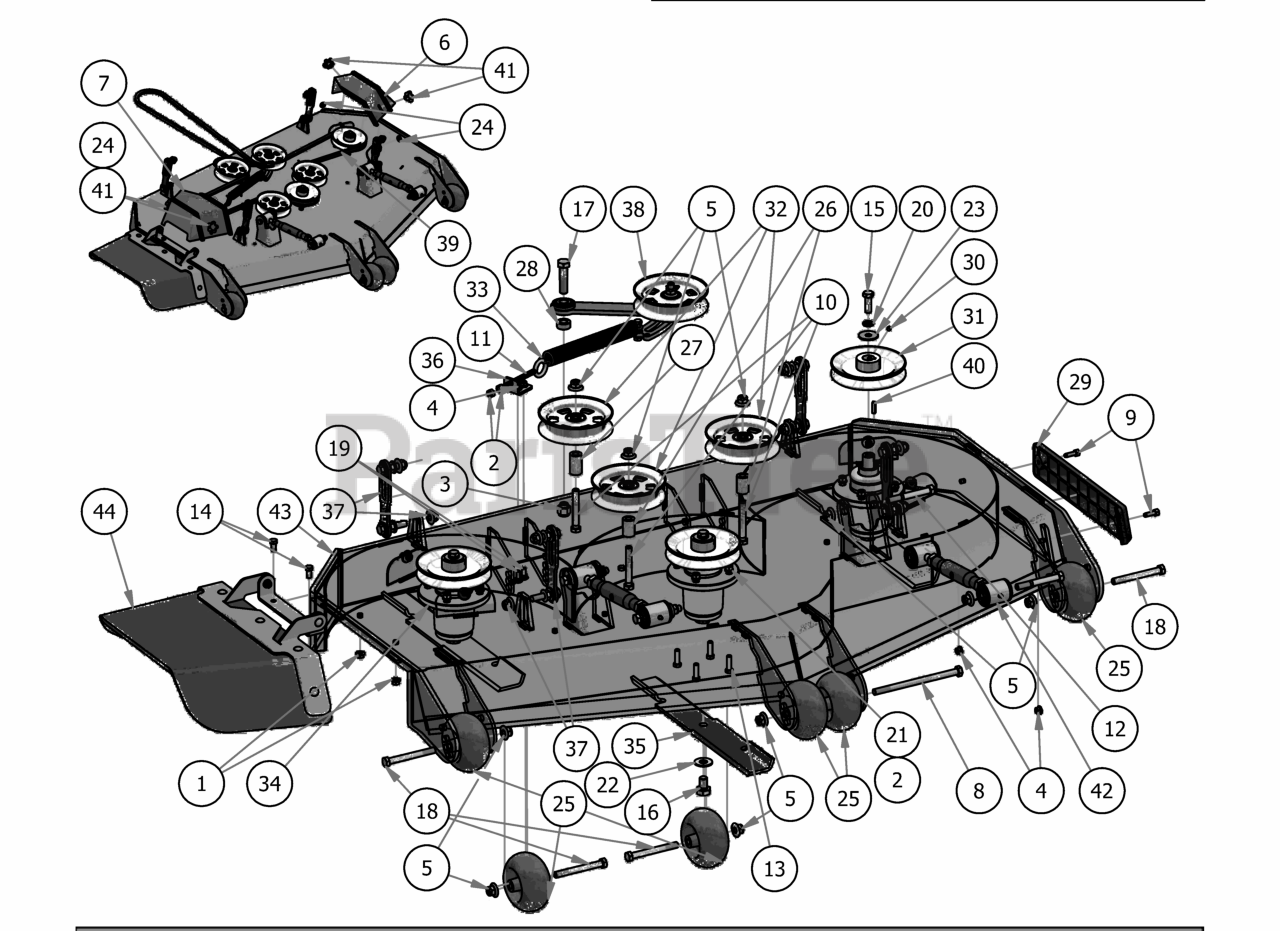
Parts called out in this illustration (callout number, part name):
1	3/8" Flange Nut
2	3/8" Hex Nut
3	5/8 Std NC Nylock Nut
4	5/16" Nylon Flange Nut
5	1/2-13 Nylon Flange Nut
6	2019 61" Outlaw Gen2 Pulley Cover Left
7	2019 61" Outlaw Gen2 Pulley Cover Right
8	1/2-13 x 8 Hex Bolt Grade 5
9	5/16-18 x 1 GR 5 Hex Bolt Zinc
10	1/2 x 3 1/2 Flange Bolt Grade 8
11	4" 3/8-16 Eye Bolt
12	1/2" x 4" Bolt (Grade 8)
13	3/8" x 1 1/4" Hex Bolt
14	3/8" x 3/4" Hex Bolt
15	1/2"-20 x 1 1/2 - Grade 5 Fine Thread Bolt
16	5/8" x 1 1/2" Grade 8 Hex Bolt (Fine)
17	5/8" x 2 1/2" Grade 5 Hex Bolt (Coarse)
18	1/2" x 4 1/2" Bolt
19	5/16" x 7/8" Carriage Bolt
20	1/2" Lock Washer
21	3/8" Lock Washer
22	5/8'' Flat Washer
23	1/2" Belleville Washer
24	.360 ID Plastic Washer-Black
25	2019 Deck Wheel
26	.502 ID X .750 OD X 1.500 Long Spacer
27	1 3/4" Pulley Spacer
28	5/8" x 1/" Collar W/One Set Screw
29	REVISED TRIM BUMPER_20180226
30	5/16 Set Screw
31	6 1/4" Drive Pulley
32	5-3/4 Idler Pulley
33	2019 Outlaw Gen2 Deck Spring
34	OUTLAW SPINDLE ASSEMBLY
35	61 inch Fusion Blade
36	2019 Deck Eye Bolt Tab
37	Deck Hangar Assembly
38	2019 Renegade Deck Idler
39	Deck Belt for 61" Renegade
40	1/4" x 1" Key
41	5/16" Knob
42	Turnbuckle
43	2019 Sloped 61" Deck
44	2019 Outlaw Gen2 Chute Assembly
